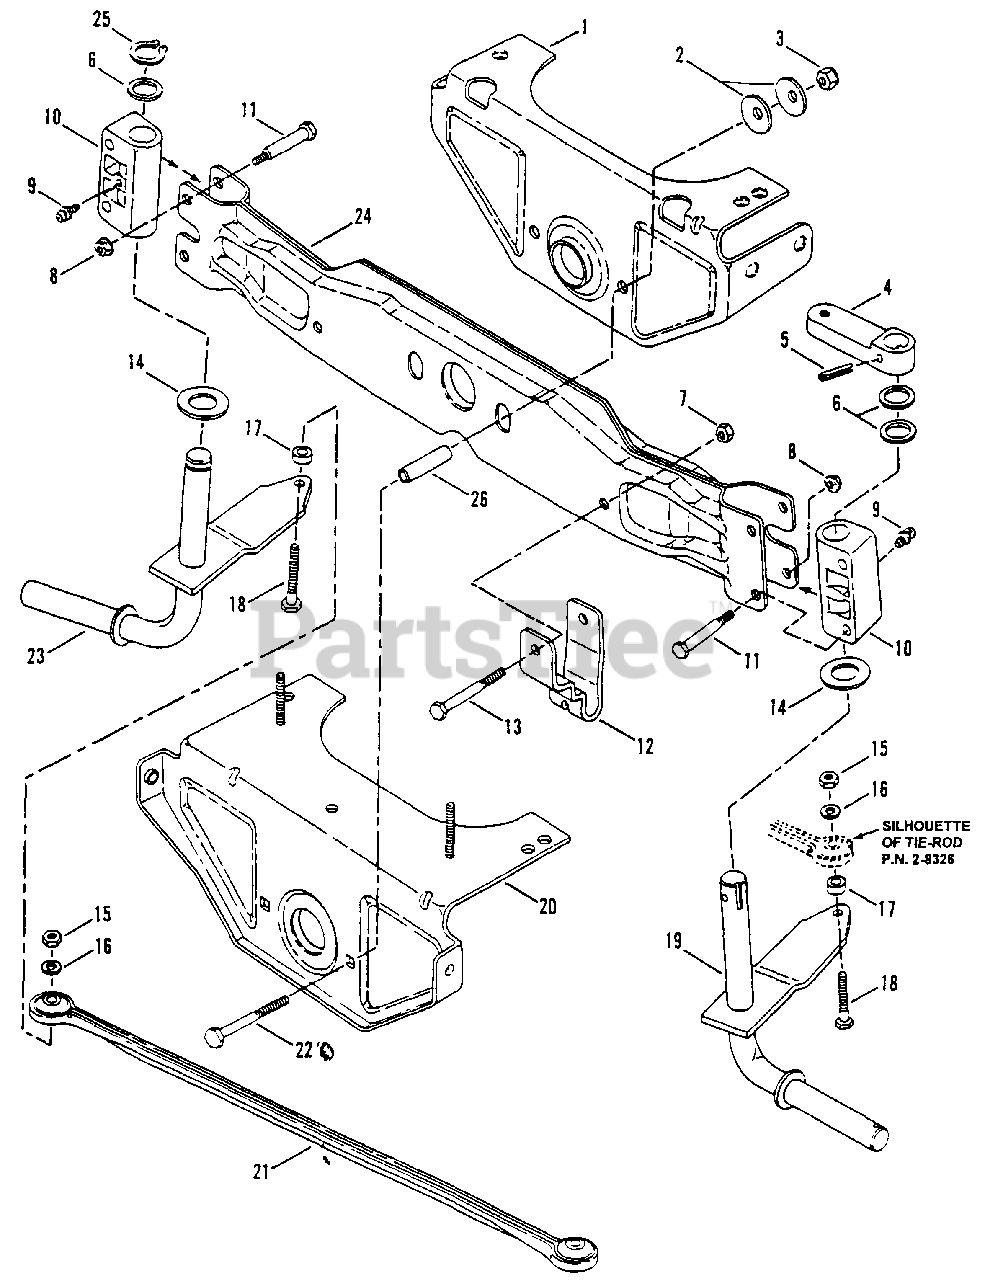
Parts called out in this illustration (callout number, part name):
1	BRACKET, Axle (Rear)
2	WASHER, Cone
3	NUT, 3/8-16 Nyloc
4	ARM, Steering
5	ROLL-PIN, 1/4 x 1 1/4"
6	WASHER, Shim
7	NUT, 5/16-18 Center Lock
8	NUT, 1/4-20 Hex Flange Top-Lock
9	LUBE FITTING, Straight (press-fit for .187 dia. Hole)
10	BEARING, Spindle
11	BOLT, 1/4-20 x 1 41/64" Shldr.
12	BRACKET, Deck Hanger
13	SCREW, 5/16-18 x 2 1/2" Hex Head Cap
14	WASHER, Thrust
15	NUT, 3/8-16 Hex, Grade 5
16	WASHER, 3/8 Split Lock
17	SPACER, Tie-Rod
18	SCREW, 3/8-16 x 1 1/2" Hex Head Cap, Grade 5
19	SPINDLE ASSEMBLY, Left Hand, Short
20	BRACKET ASSEMBLY, Axle (Front)
21	TIE-ROD
22	BOLT, 3/8-16 x 3" Hex Head
23	SPINDLE ASSEMBLY, Right Hand, Short
24	AXLE, Front
25	RING, Retaining
26	SPACER
